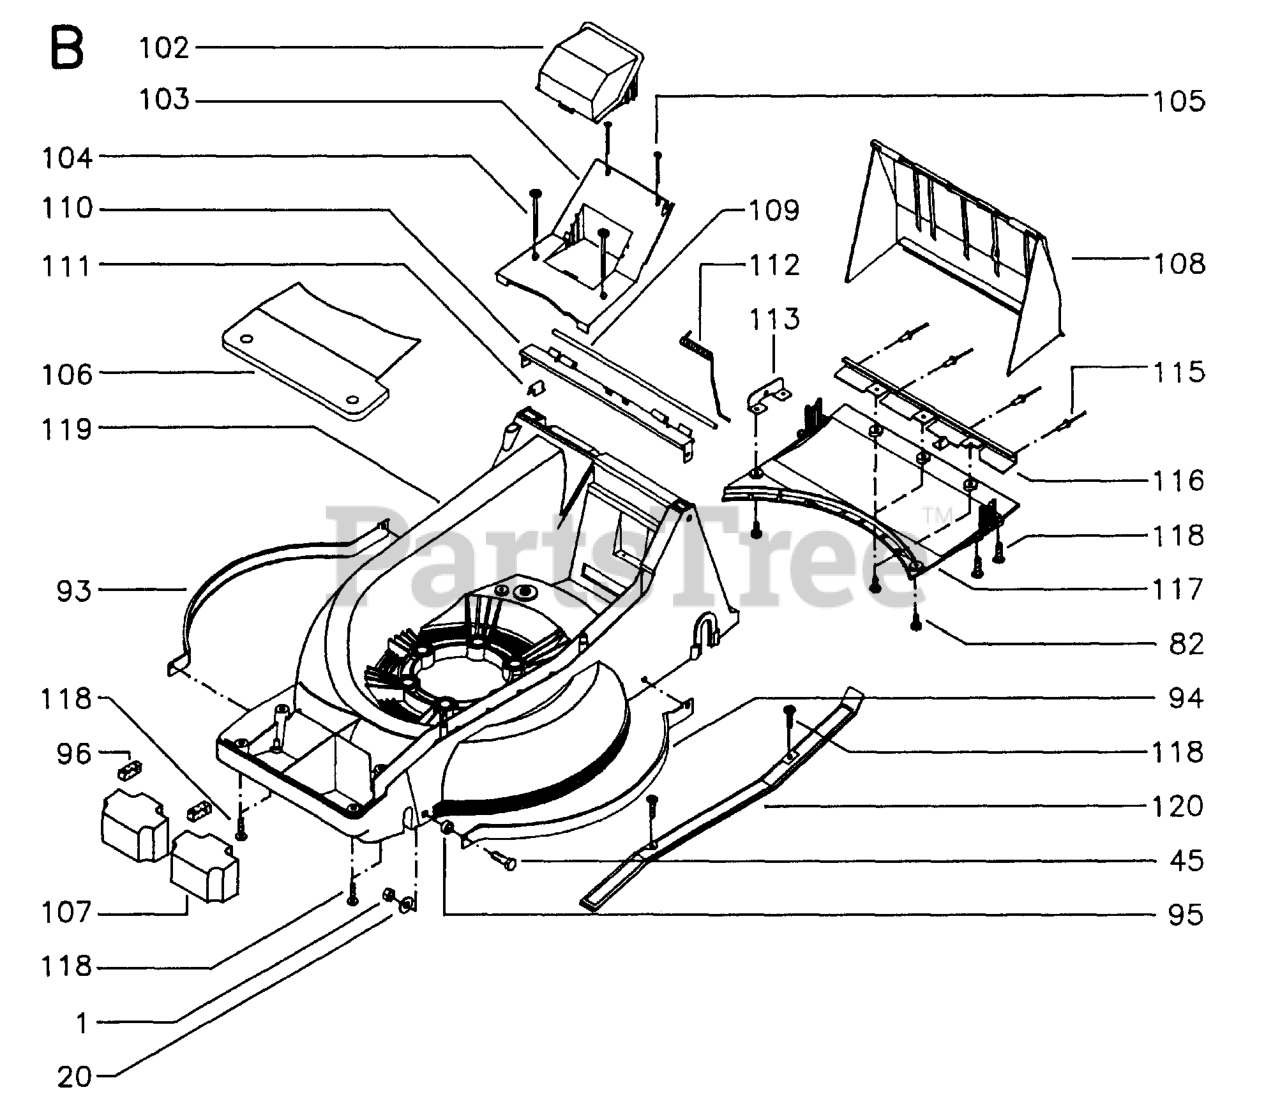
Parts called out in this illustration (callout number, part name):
1	LOCKNUT M8
45	SCREW M6S 8X25
93	DECK PROTECTOR RH
94	DECK PROTECTOR LH
106	DECK FRONT COVER
107	COUNTERWEIGHT
110	BRACKET
113	BRACKET
120	COVER
